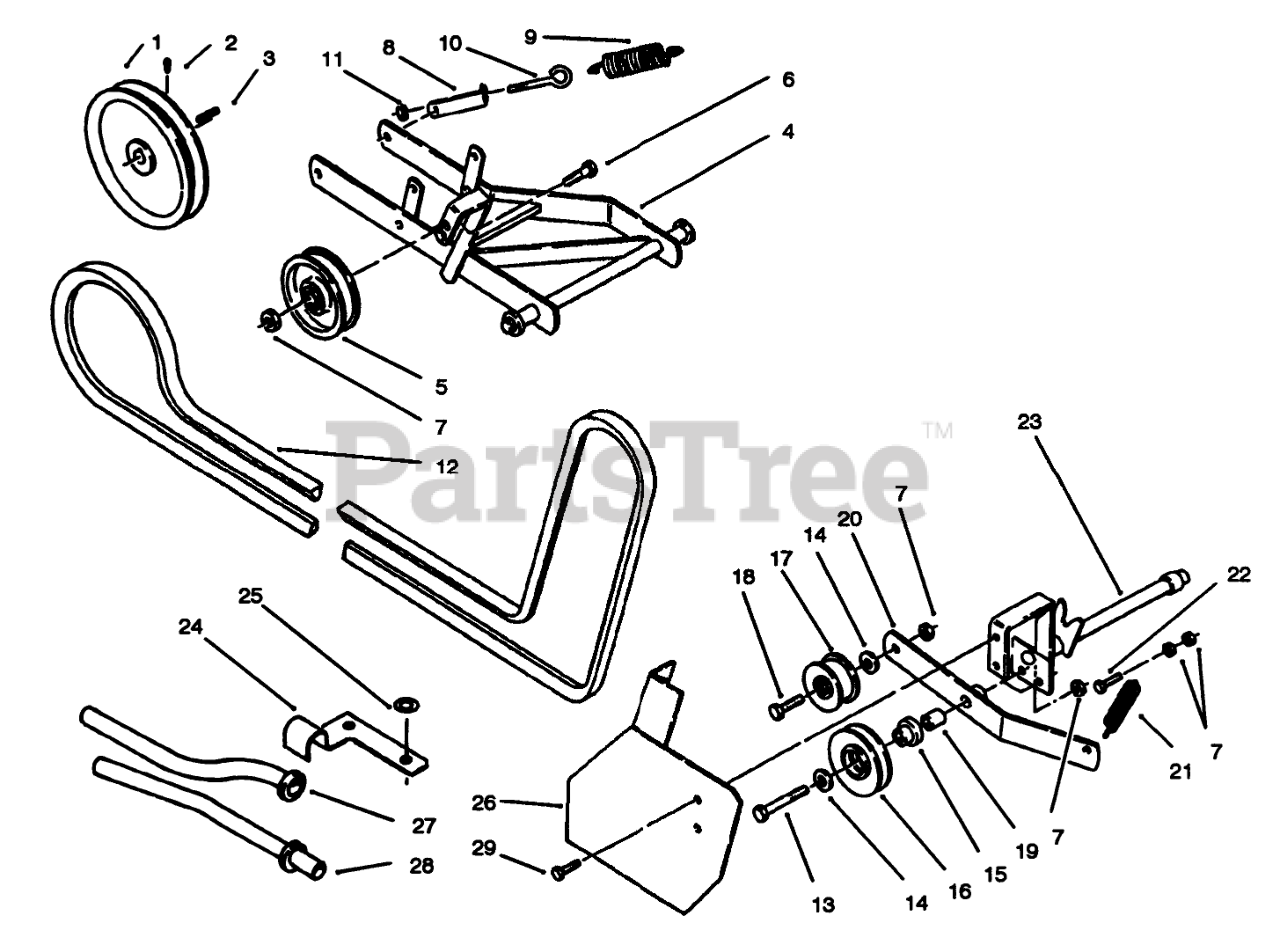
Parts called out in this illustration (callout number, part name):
1	Pulley
2	KEY-STRAIGHT
3	Set Screw
4	Hitch
5	Flat Idler
6	HEX HD CAP SCREW
7	NUT-HEX
8	Bracket-Spring
9	SPRING
10	EYEBOLT
11	NUT-LOCK, NI
12	V-BELT
13	SCREW-HH
14	WASHER
15	SPACER
16	Pulley-V
17	IDLER PULLEY
18	SCREW-HH
19	SPACER
20	ASSY IDLER ARM R
21	SPRING-BRAKE
22	SCREW-HH
23	ASSY SUPPORT R
24	CLAMP-CONDUIT R
25	WASHER
26	ASM: FRONT IDLER R
27	TUBE-CONDUIT R
28	Conduit-Mech. Trans.
29	Bolt
